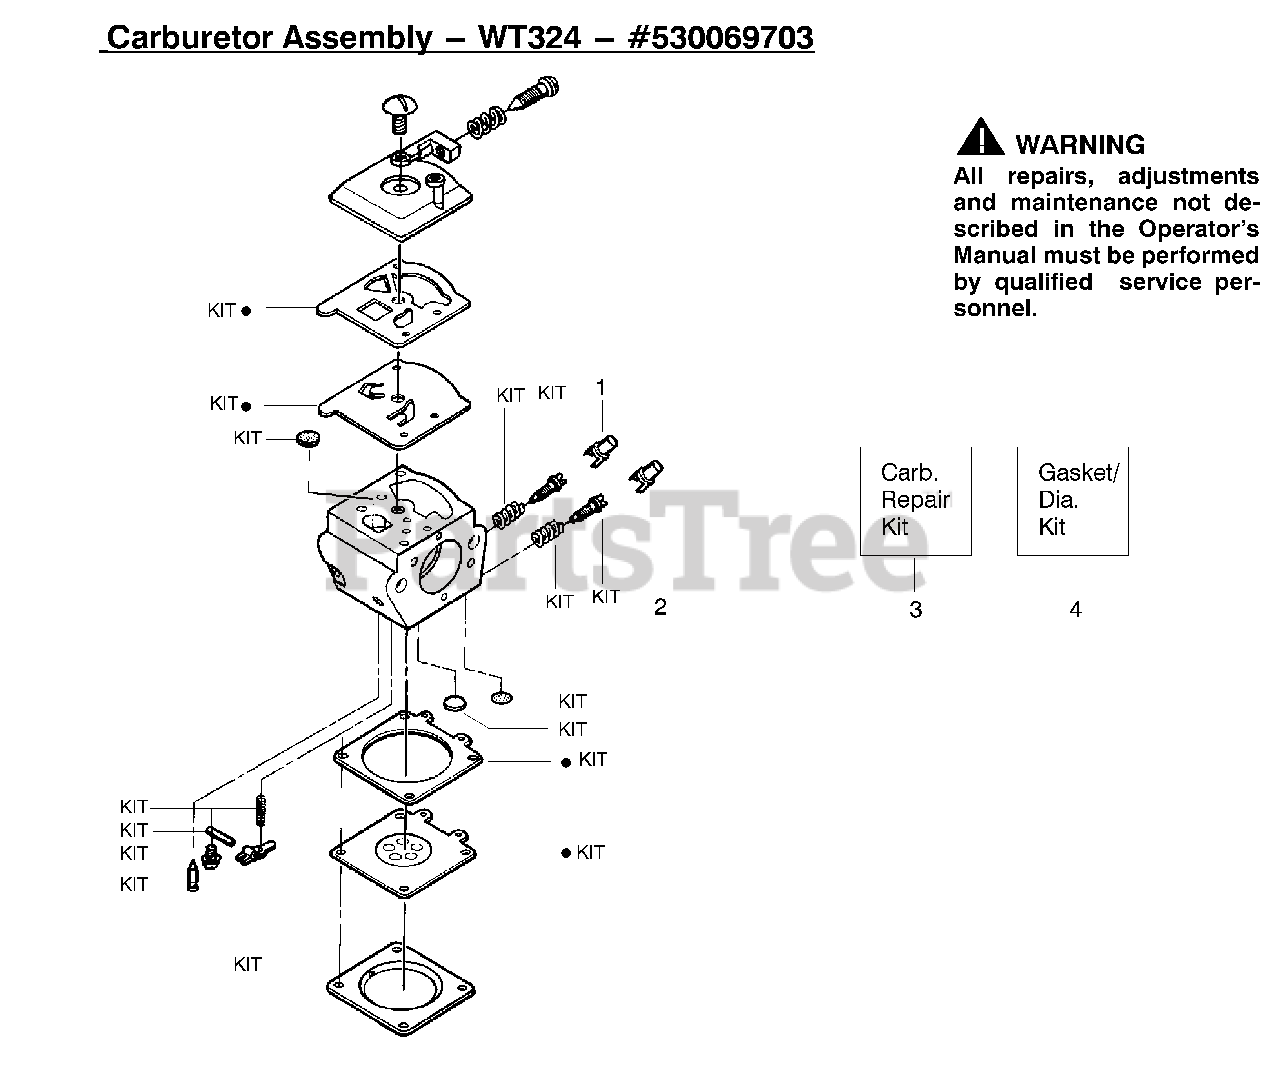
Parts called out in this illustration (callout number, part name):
1	Limiter Cap-High
2	Limiter Cap-Low
3	Carburetor Repair Kit
4	Gasket Diaphragm Kit
